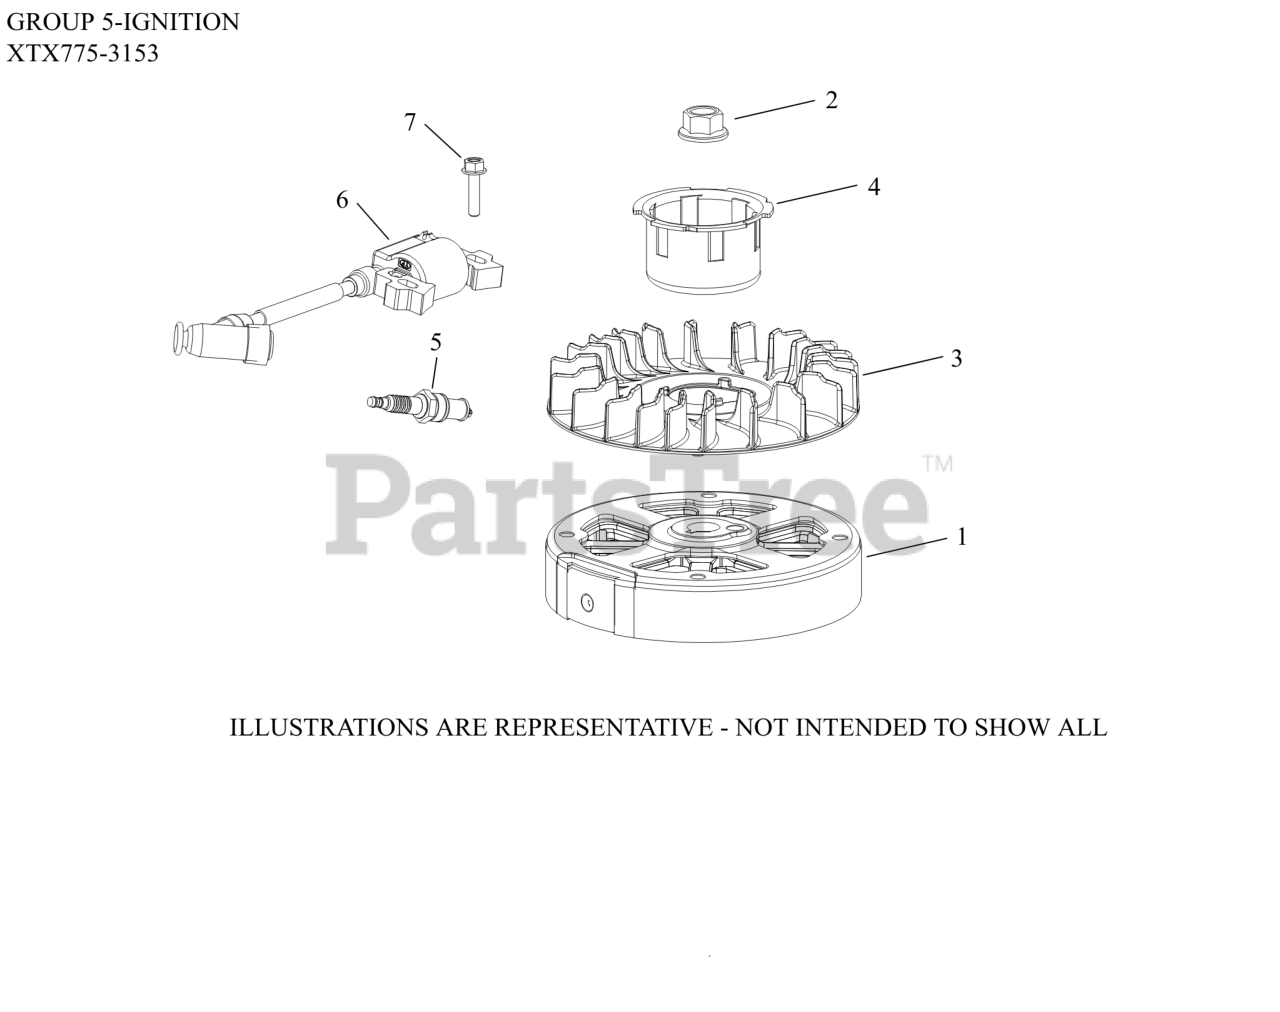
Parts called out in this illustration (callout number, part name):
1	FLYWHEEL ASSEMBLY
2	NUT, FLYWHEEL (W/SERRATIONS)
3	FAN, FLYWHEEL
4	CUP, STARTER DRIVE
5	PLUG SPARK 12MM RFI
6	MODULE IGN (#1458416S)
7	SCREW, M6 X 25-(#25086436S)
